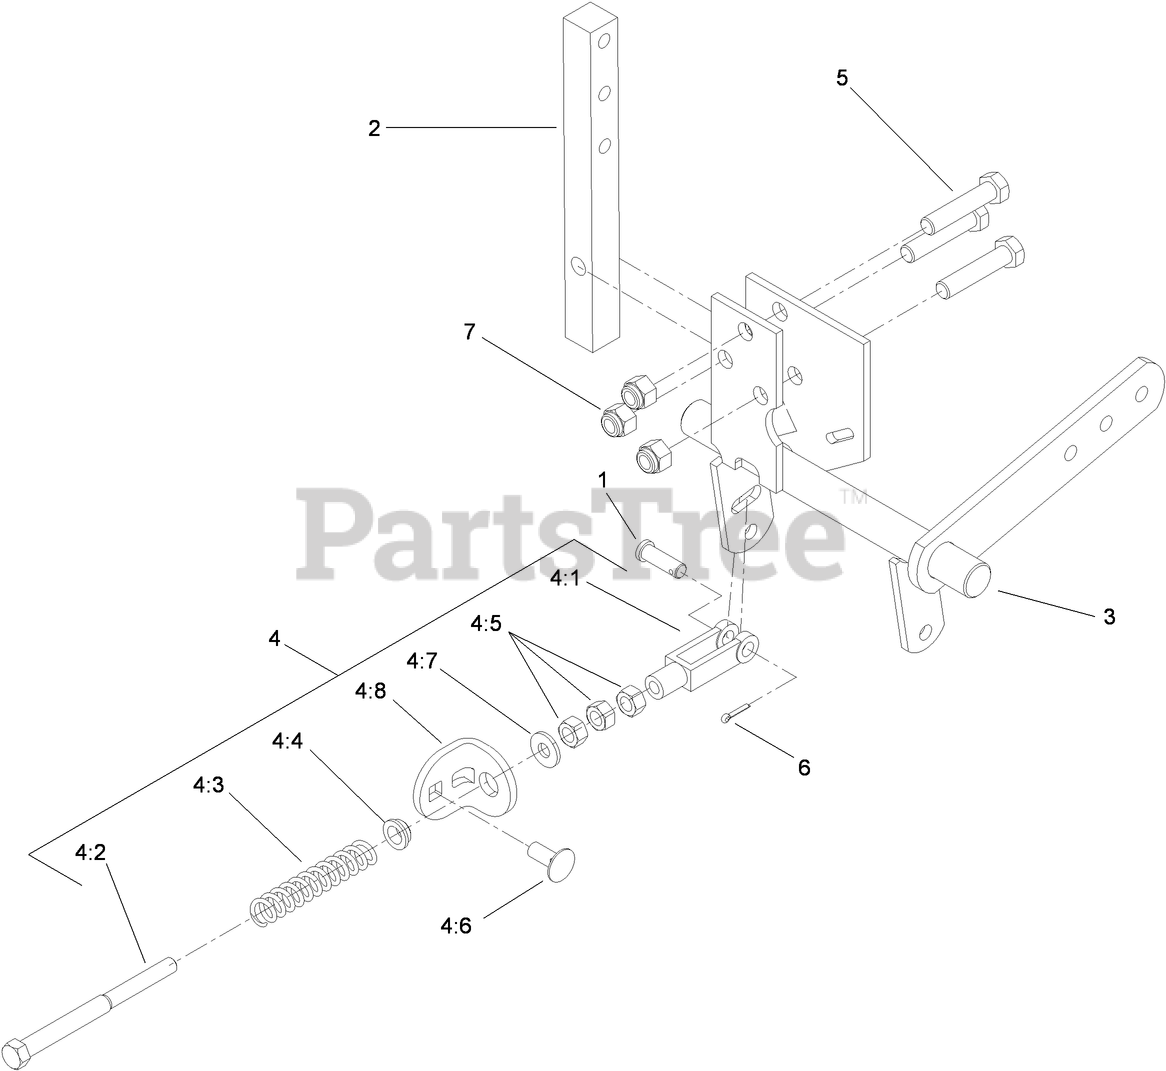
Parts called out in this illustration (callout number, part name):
1	PIN-CLEVIS
2	ARM-SHAFT, CONTROL
3	CONTROL-MOTION, RH
4	NEUTRAL RETURN ASM
4:1	YOKE-ADJUSTABLE
4:2	BOLT-RETURN, NEUTRAL
4:3	SPRING-RETURN, NEUTRAL
4:4	BUSHING-NYLON, FLANGED
4:5	NUT-HEX
4:6	SCREW-CARR
4:7	WASHER-FLAT
4:8	TAB-ADJUSTMENT
5	SCREW-HH
6	PIN-COTTER
7	NUT-LOCK, NI
